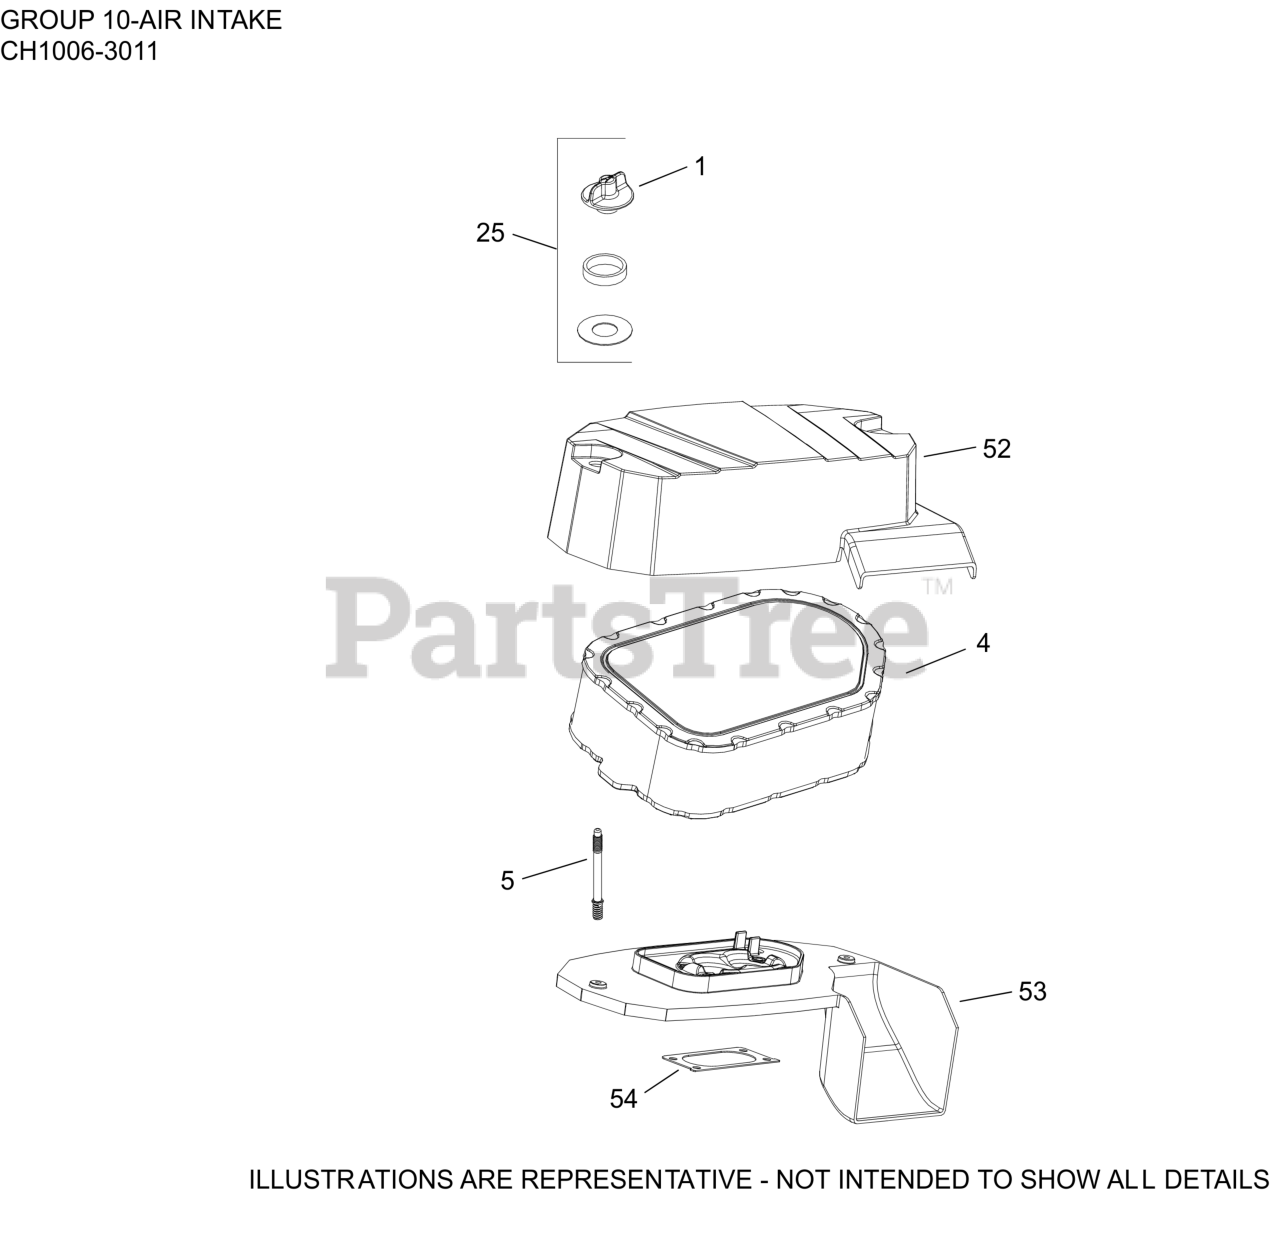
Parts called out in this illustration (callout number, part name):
1	KNOB, COVER
4	ELEMENT, AIR FILTER (LPAC)
5	STUD, AIR CLEANER BASE
25	KIT, KNOB W/SEAL
52	BASE, AIR CLEANER ASSEMBLY
53	COVER, AIR CLEANER
54	GASKET, AIR CLEANER ELBOW
